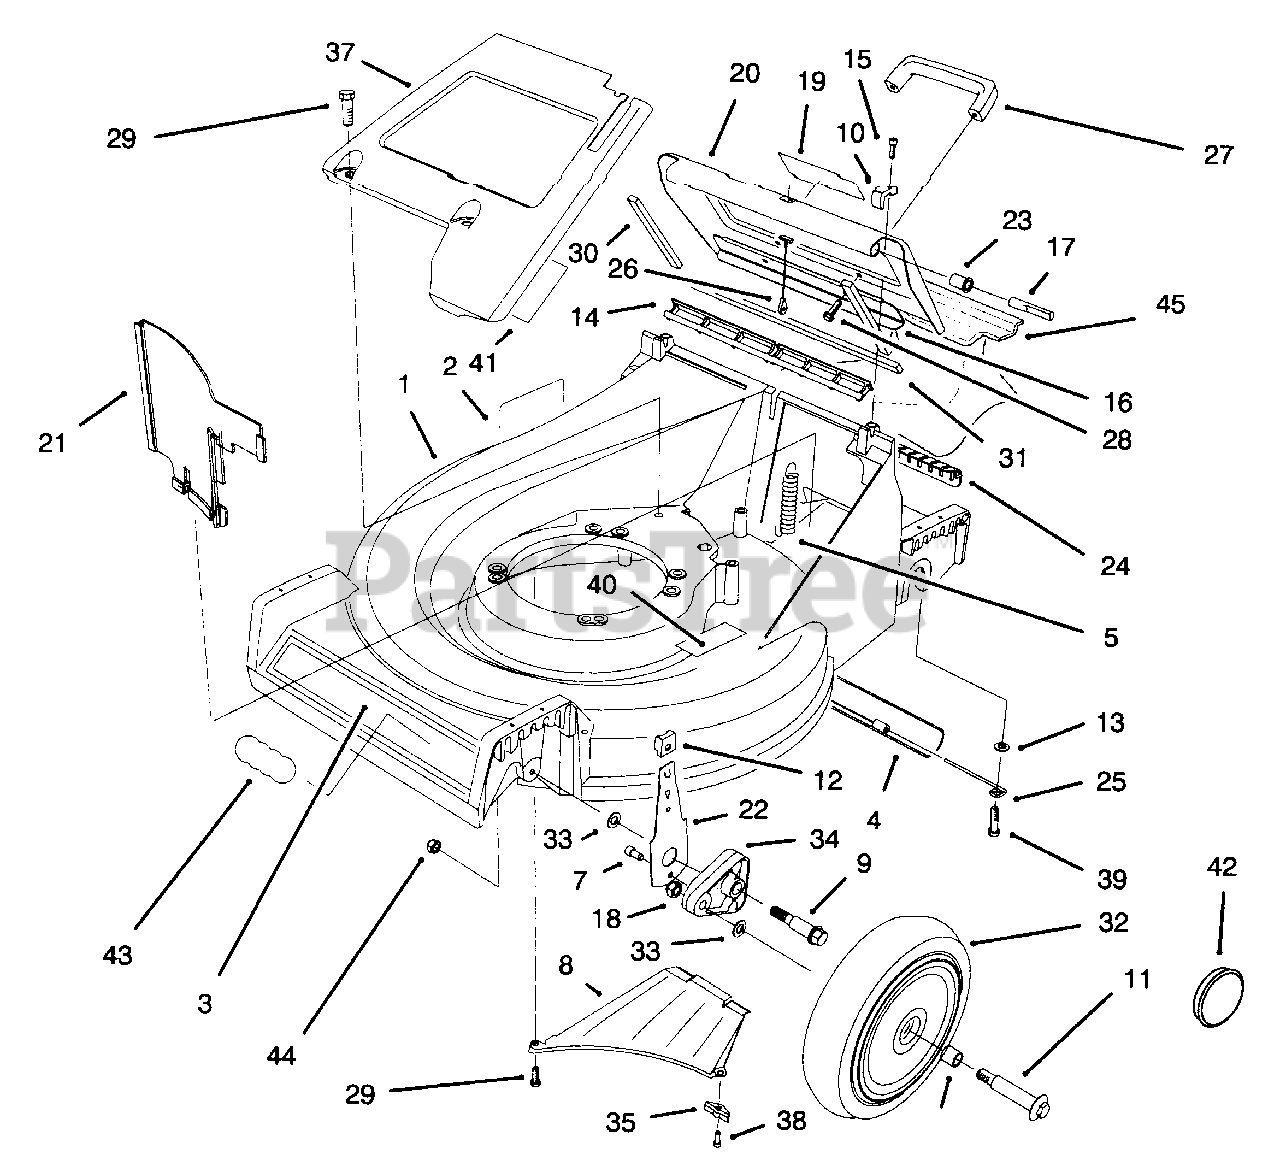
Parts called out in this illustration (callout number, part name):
1	Housing-Deck (Incl. Ref. #2 & 40)
2	Decal-Danger
3	Decal-Deck
4	Shield-Trailing
5	Spring-Extension
7	Screw-Hex Hd.
8	Ramp-Discharge
9	Screw-Shoulder
10	Clamp-Hinge
11	Bolt-Wheel
12	Knob-Arm
13	Washer-Flat
14	Seal-Door
15	Screw-Thread Form.
16	Brace-Door
17	Pin-Hinge
18	Nut-Lock
19	Decal-Warning
20	Door-Discharge
21	Panel-Vertical
22	Spring Arm Ass'y-Front
23	Bushing-Door
24	Cover-Access
25	Hanger-Shield
26	Cable-Door
27	Handle-Hood
28	Screw-Tapping
29	Screw-Tapping
30	Seal-Door Side
31	Seal-Door End
32	Tire & Wheel Assembly-8"
34	Arm-Pivot
35	Bracket-Discharge Ramp
37	Panel-Screen
38	Screw-Thread Form.
39	Bolt-Shoulder
40	Decal-Warning
41	Decal-Instructions
43	Decal-Applique
44	Nut-Lock
45	Plug-Mulching
